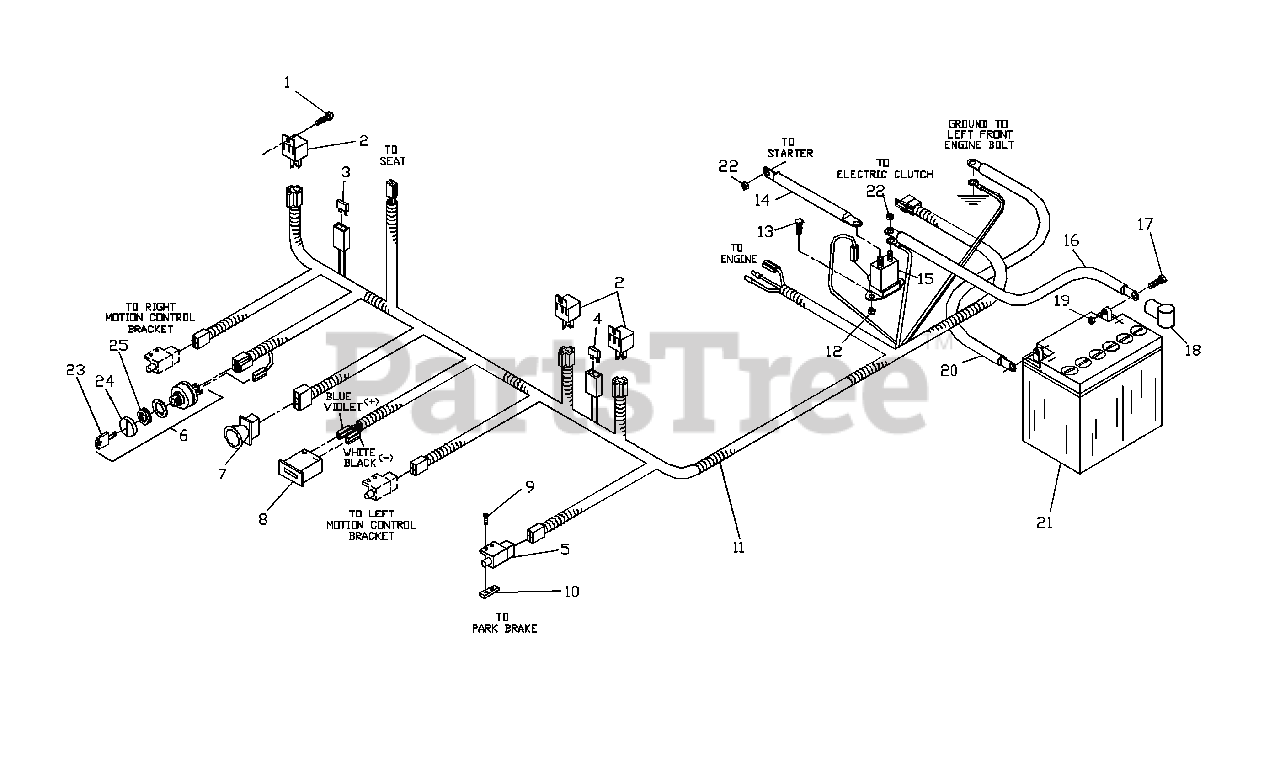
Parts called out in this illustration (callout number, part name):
1	#10 X 1/2 SELF TAPPING
3	7.5 AMP 32 VOLT ATO FUSE
4	20 AMP 32 VOLT ATO FUSE
5	INTERLOCK SWITCH
6	IGNITION SWITCH
7	BLADE SWITCH
8	HOUR METER
9	#10-24 X 5/8
10	TAPPED PLATE
11	WIRING HARNESS
12	NUT 1/4C CENTERLOCK
13	HCS 1/4C X 5/8
14	CABLE POSITIVE
16	CABLE POSITIVE, LONG
17	HCS 5/16C X 3/4
19	NUT 5/16C CENTERLOCK
20	CABLE NEG.
21	BATTERY
22	NUT 1/4C NYLOC
23	KEY, PADDED
